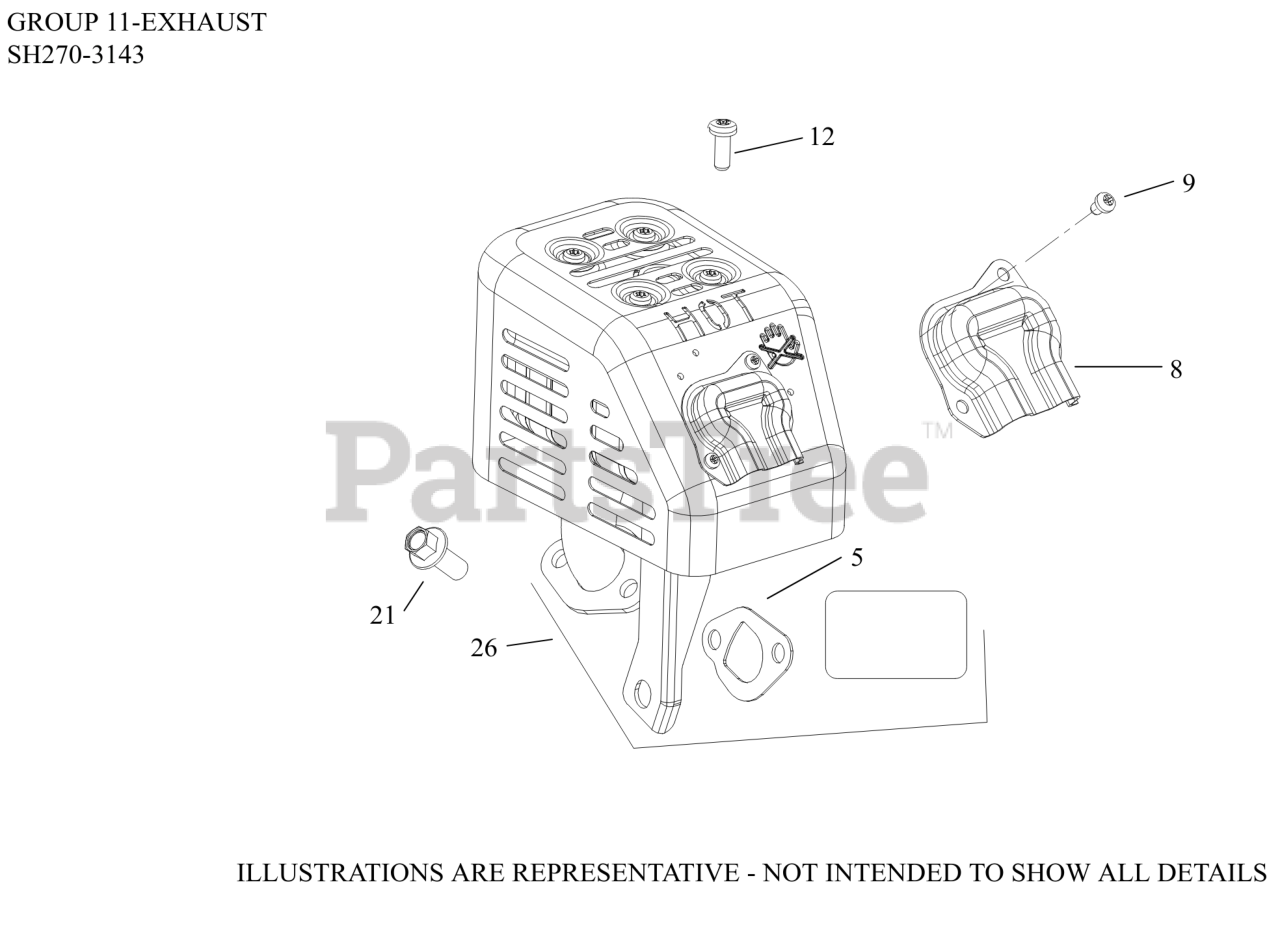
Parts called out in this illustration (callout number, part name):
5	GASKET, EXHAUST
8	DEFLECTOR, EXHAUST - USE 18 730 01-S
9	SCREW, SPARK ARRESTOR
12	SCREW, M5 X 10
21	SCREW, M8 X 20
26	KIT, MUFFLER
